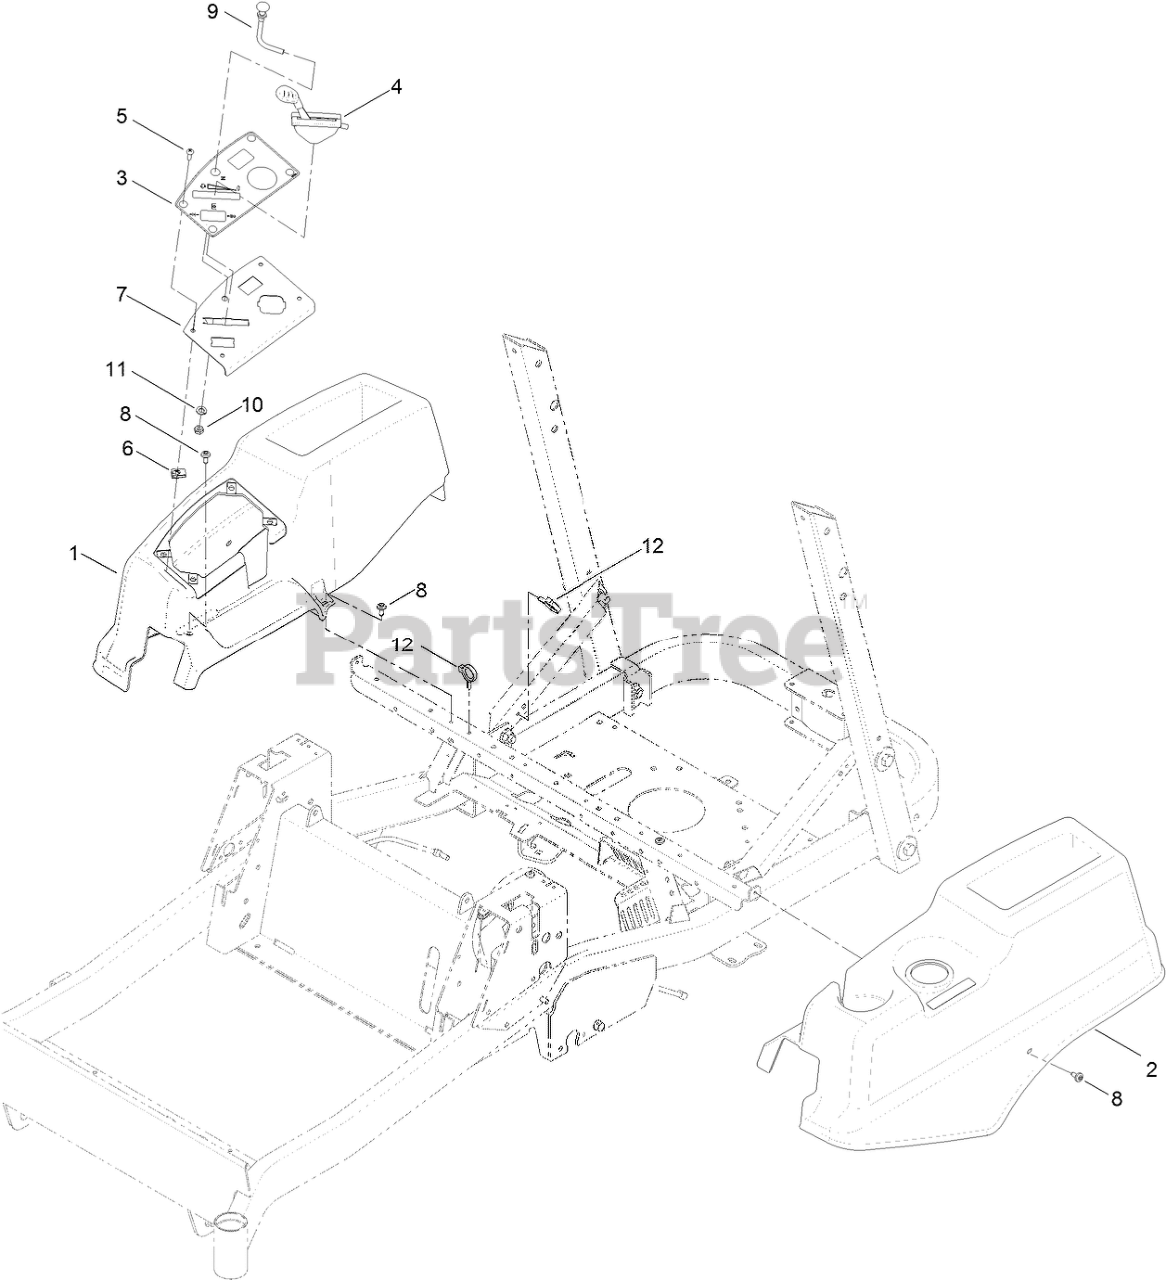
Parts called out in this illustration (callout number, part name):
1	POD-RH
2	POD-LH
3	DECAL-PANEL, CONTROL
4	CABLE-THROTTLE
5	SCREW-PRH
7	PANEL-CONTROL
8	SCREW-SHOULDER
9	CABLE-CHOKE
10	WASHER-LOCK
11	NUT-HJ
12	CLAMP-HOSE
